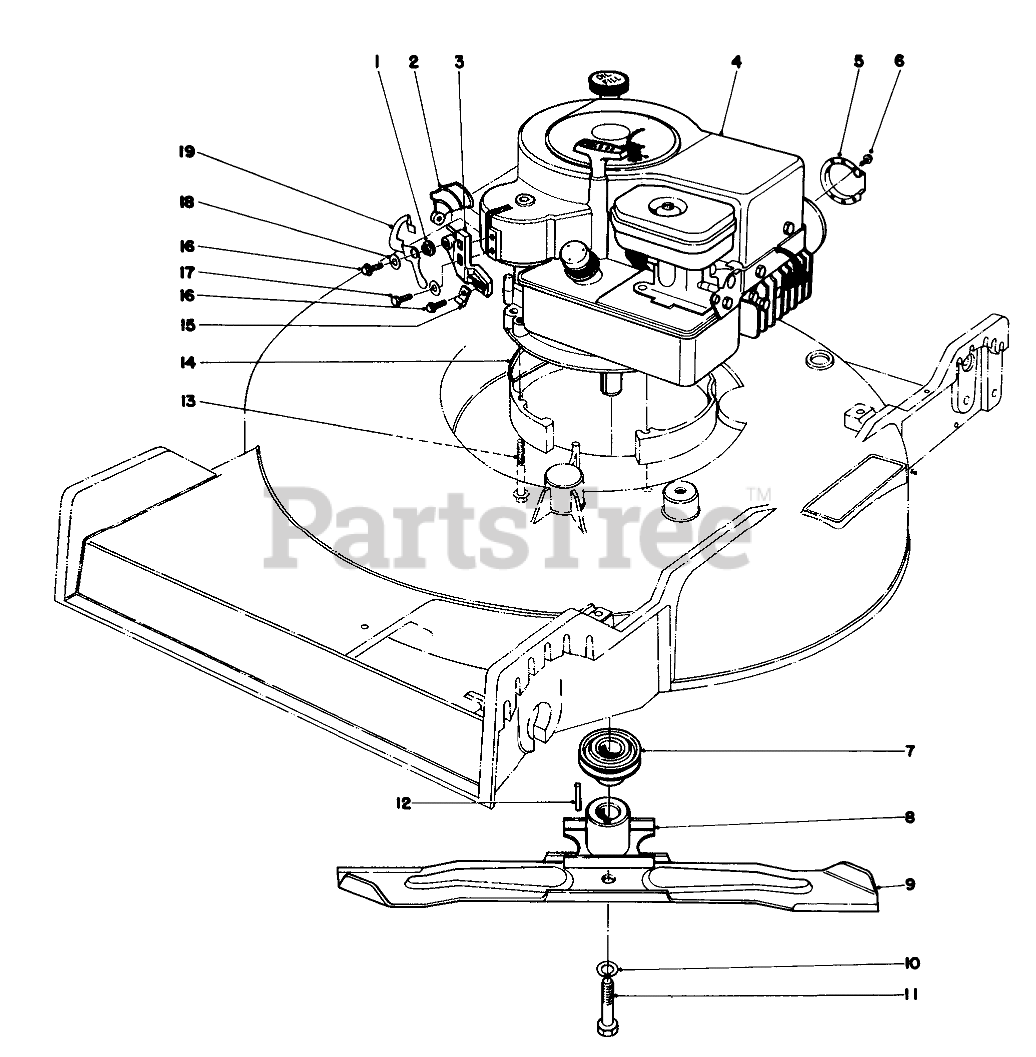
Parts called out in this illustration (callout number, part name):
1	BUSHING
2	INTERLOCK LEVER
3	CABLE & PIVOT BLOCK
4	Engine
5	Deflector
6	SCREW W/ENGINE
7	Pulley
8	BLADE RETAINER WA(BLACK)
9	Blade
10	WASHER-LOCK
11	BLADE SCREW
12	KEY-SQUARE
13	3/8-16 X 2 CAPSCREW
14	HOUSING CAP
15	CLAMP
16	SCREW-HWHTF
17	SCREW-SHWH
18	WASHER-FLAT
19	CAM INTERLOCK
